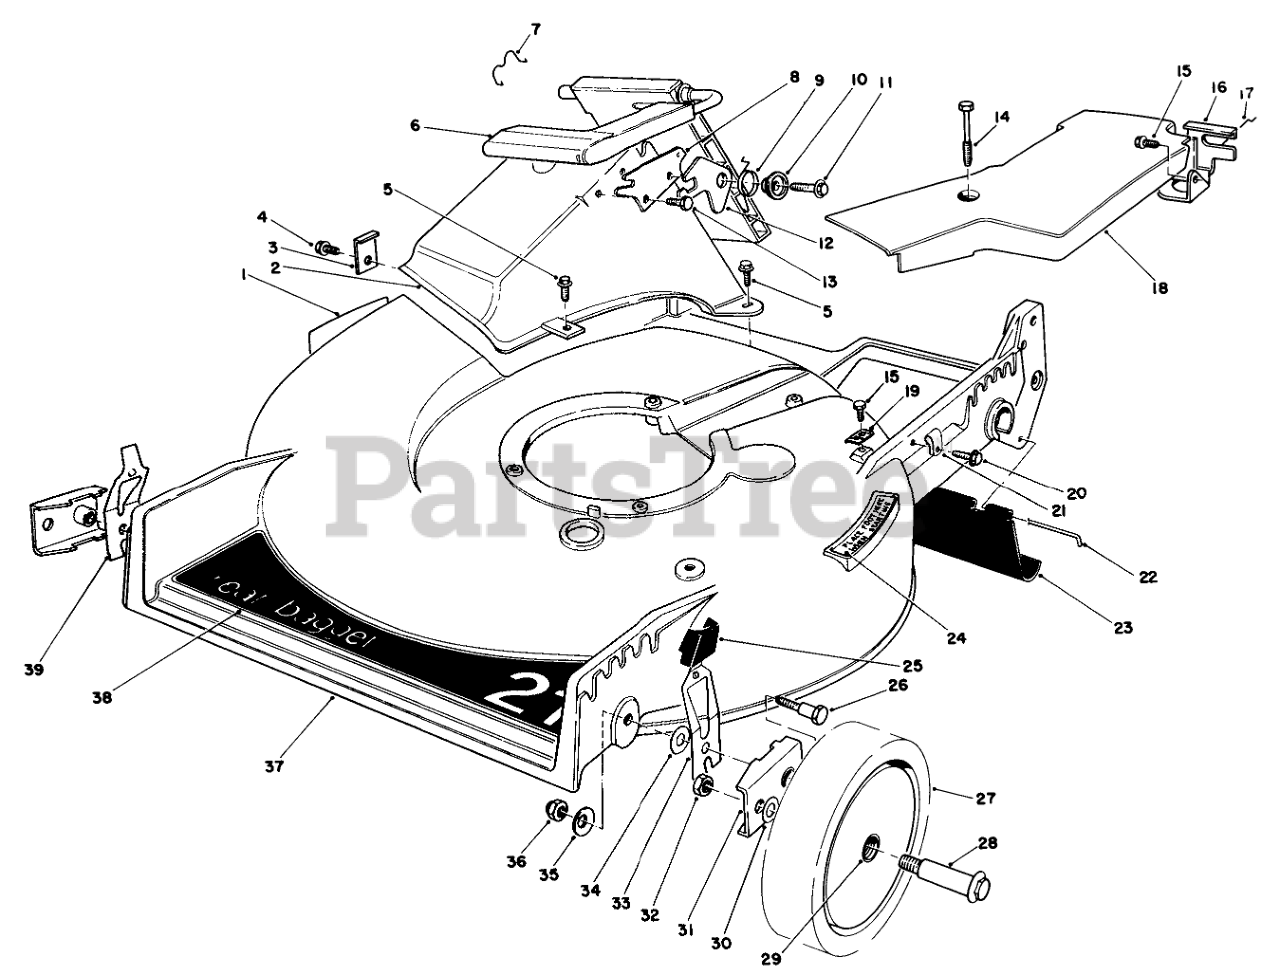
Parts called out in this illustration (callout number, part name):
1	DECAL-DANGER
2	Tunnel Discharge
3	TUNNEL CLIP
4	SCREW
5	SCREW-HWH
6	Discharge Door Assembly
7	DOOR RET SPRING
8	DOOR LATCH PLATE
9	TORSION SPRING
10	DOOR SPACER
11	SCREW-HWH
12	SAFETY LATCH
13	SCREW-PLASTITE
14	SCREW-HHFTF
15	SCREW-HWHTF
16	Bracket-Traction Adj.
17	RETAINER-CABLE
18	Cover-Belt
19	Cable Clamp
20	SCREW
21	CLAMP-CABLE
22	ROD-SHIELD
23	SHIELD-TRAILING
24	STEP PAD DECAL
25	KNOB-ARM
26	PIVOT SCREW
27	Wheel & Tire Assembly (Incl. Ref. #29)
28	WHEEL BOLT
28	BOLT-WHEEL
29	BUSHING
30	WASHER
31	HP PIVOT ARM ASM
32	NUT-LOCK
32	Nut
33	L. HP SPRING ARM ASM
34	WASHER-PIVOT
35	WASHER-BELLEVILLE
36	NUT-LOCK, NI
37	Housing-21" (Incl. Ref. #1, 5 & 24)
38	DECK DECAL
39	R HP SPRING ARM ASM
